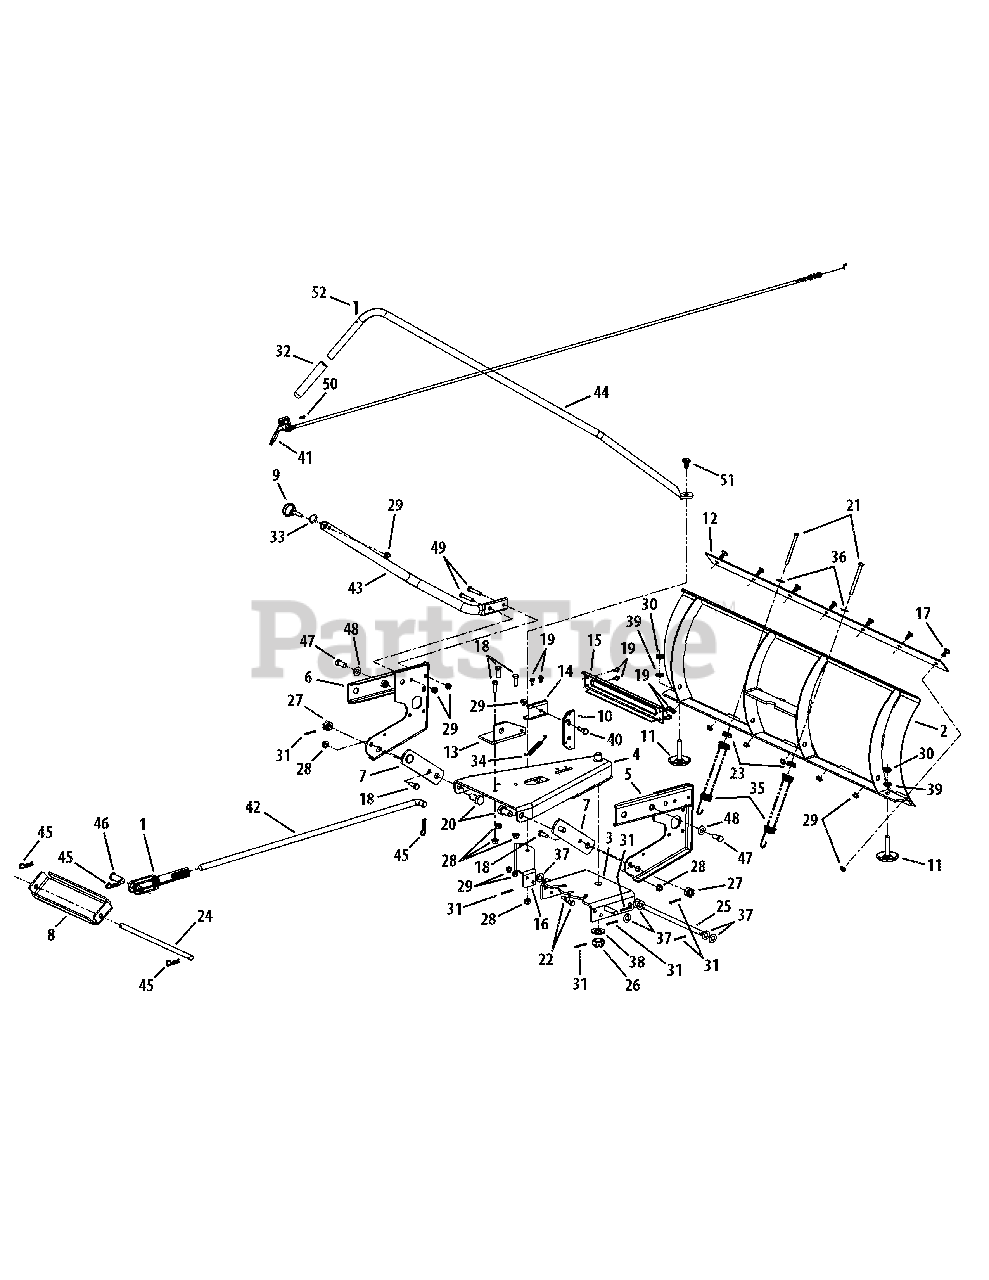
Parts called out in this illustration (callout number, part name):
1	Clevis Assembly Adjustment
2	Blade Dozer Assembly
3	Blade Pivot Assembly
4	Blade Frame Assembly
5	Hitch Blade Assembly, RH
6	Hitch Blade Assembly, LH
7	Arm Mounting Assembly
8	Lift Bracket Assembly
9	Eyebolt Assembly
10	Lock Blade Plate Assembly
11	Skid Shoe Assembly
12	Cutting Edge Plate
13	Front lift Bracket
14	Pivot Bracket
15	Snowblade Support Bracket
16	Blade Adjustment Arm
17	Carriage Bolt, 5/16-18 x .750
18	Hex Cap Screw, 3/8-16 x 1.00
19	Self Tapping Screw, 1/4-20 x .500
20	Hex Cap Screw, 5/8-18 x 1.31
21	Hex Cap Screw, 5/16-18 x 3.50
22	Hex Cap Screw, 5/16-18 x .75
23	Spring Insert
24	Rod, .500 Dia. x 12.50 Lg.
25	Rod, .500 Dia. x 10.428 Lg.
26	Slotted Nut, 3/4-16
27	Slotted Hex Nut, 5/8-18
28	Nut, Flange Lock, 3/8-16, Top Lock
29	Nut, Flange Lock, 5/16-18
30	Jam Nut, 1/2-13
31	Cotter Pin, 1/8 x 1.25
32	Foam Grip
33	Button Plug, .750 ID
34	Extension Spring, .38 OD x 3.25 Lg.
35	Extension Spring, 1.25 Dia. x 6.7 lg.
36	Flat Washer, .349 x .879 x .063
37	Flat Washer, .50 x 1.00 x .060
38	Flat Washer, .76 x 1.50 x .120
39	Lock Washer, 1/2
40	Shoulder Screw, .405 x .435, 5/16-18
41	Blade Release Cable
42	Lift Rod, .625 Dia.
43	Handle Support Tube
44	Blade Pivot Handle
45	Cotter Pin, 1/8 x 1.75
46	Clevis Pin
47	Hex Cap Screw, 7/16-14 x 1.00
48	Bevel Washer, .45 x 1.00 x .062
49	Hex Cap Screw, 5/16-18 x 1.75
50	Weld Nut, #10-24
51	Shoulder Screw, 1/2 x .29
52	Machine Screw, #10-24 x 1.375
